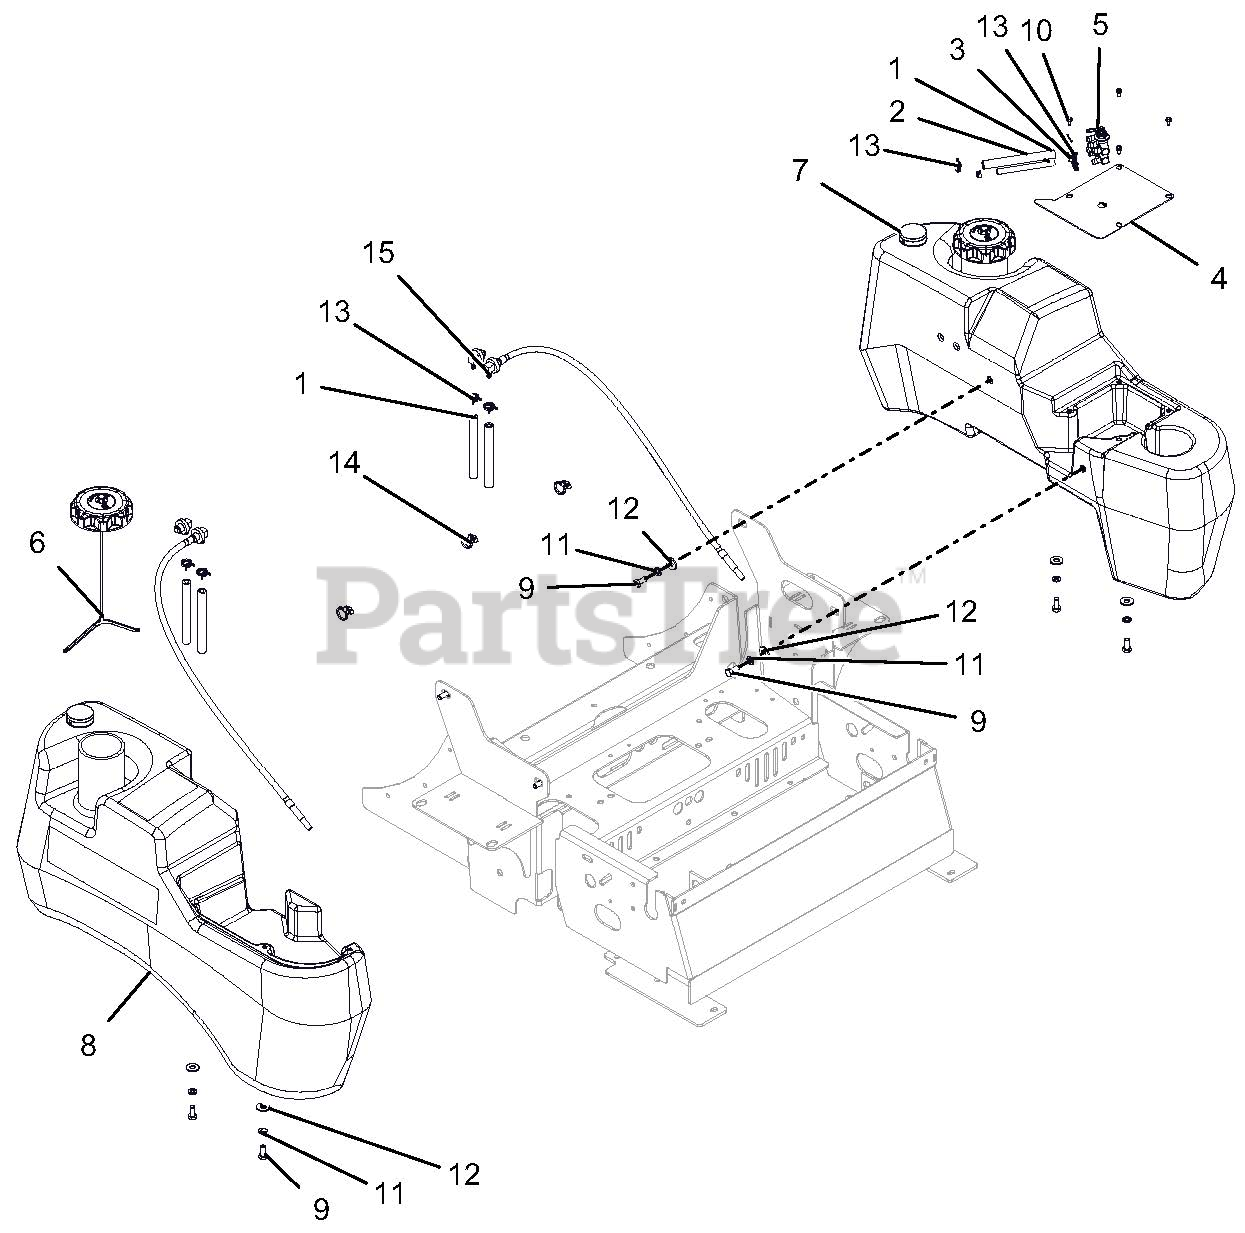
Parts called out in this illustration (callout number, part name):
1	HOSE, .31 ID X
2	HOSE, .188 ID LOW-PERM X 60.0 LG - ENGINE RETURN TO VALVE
3	CLAMP - HOSE, SPRING .188
4	PLATE, FUEL VALVE MOUNTING-RED
5	VALVE, DIESEL FUEL PT-400
6	CAP, FUEL 3.50" DIESEL YELLOW
7	ASSY-LH LARGE FUEL TANK W/MECH GAUGE-DIESEL
8	ASSY-RH LARGE FUEL TANK W/MECH GAUGE-DIESEL
9	BLT-HEX .31-18X.75 GR5 YWZC
10	SCR-MCH 10-24X.38 HWHSTAINLESS
11	WSHR-LK .31X.078 REG YWZC
12	WSHR-FL-STL.38X.875X.083 YWZC
13	HOSE, CLAMP DOUBLE WIRE
14	CABLE TIE W/ TREE, .25 HOLE
15	FUEL, LINE KIT DIESEL
